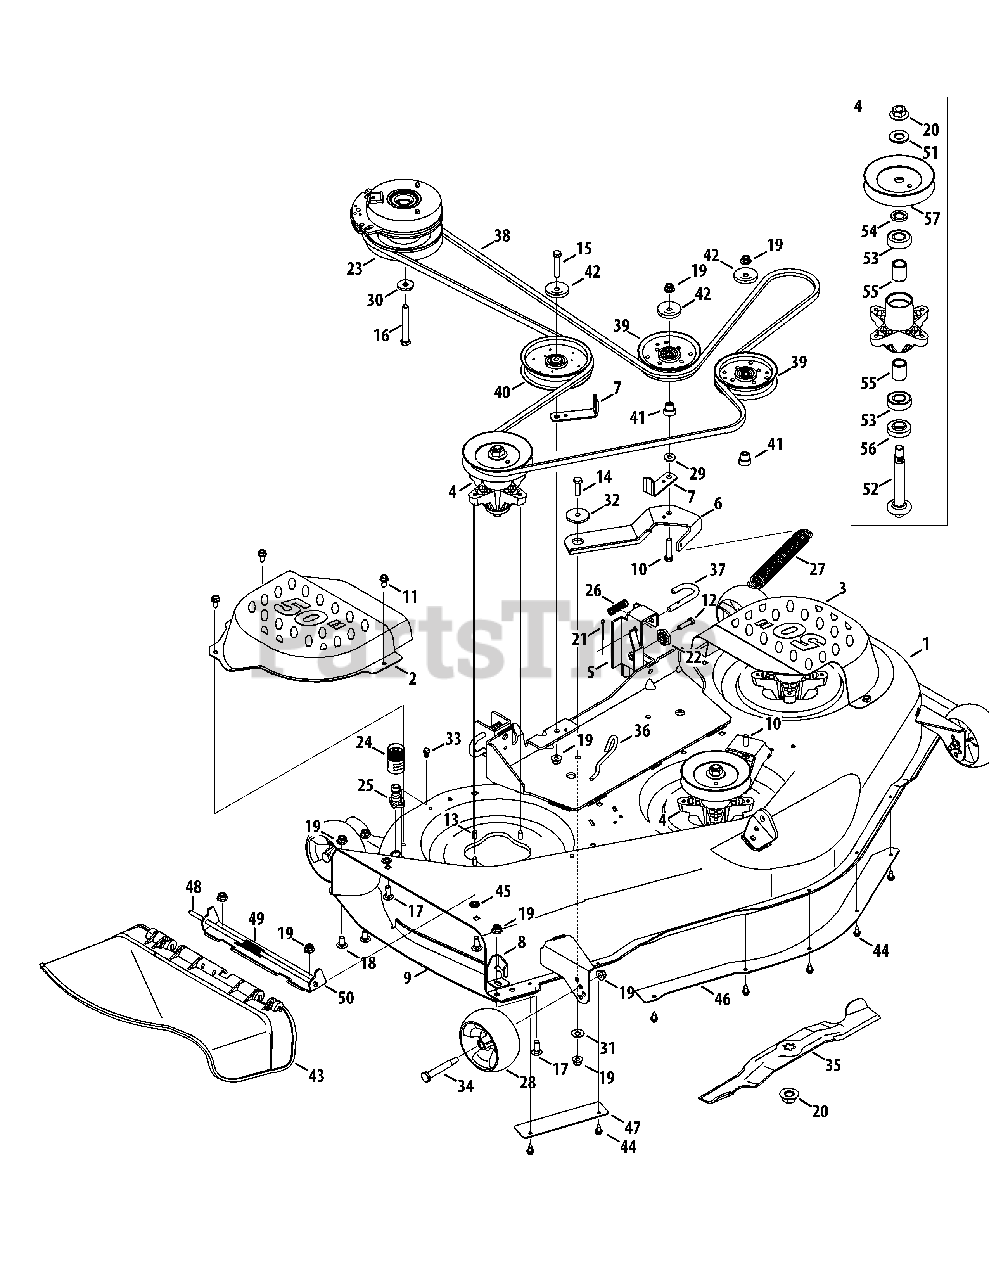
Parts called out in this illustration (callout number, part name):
2	Belt Cover, RH
3	Belt Cover, LH
4	Spindle Assembly
5	Deck Lift Bracket
6	Idler Arm
7	Bracket Belt Guard
10	Hex Cap Screw, 3/8-16 x 1.75
11	Hex Washer Screw, 5/16-18 x .750
12	Hex Cap Screw, 5/16-18 x 1.25
13	Hex Washer Screw, 5/16-18 x .750
14	Hex Cap Screw, 3/8-16 x 1.25
15	Hex Cap Screw, 3/8-16 x 2.00
16	Screw, 7/16-20 x 3.25
17	Carriage Screw, 3/8-16 x 1.00
18	Carriage Screw, 3/8-16 x .75
19	Flange Lock Nut, 3/8-16
20	Hex Flange Nut, 5/8-18
21	Cotter Pin, 5/32 x 1.25
22	Deck Adjustment Gear
23	Electric PTO Clutch
24	Water Nozzle Adapter
25	Deck Wash Nozzle
26	Compression Spring, .66 x 1.9
27	Extension Spring, 1.25 OD x 1.751
28	Deck Ball Wheel, 5.0
29	Flat Washer, .385 x .870 x .092
30	Flat Washer, .450 x 1.25 x .164
31	Bell Washer, .45 x 1.0 x .062
32	Shoulder Spacer, .884 x .190
33	Shoulder Screw, .500 x 1/4-20
34	Shoulder Screw, .5 x 2.5 x 3/8-16
35	Blade, 2 in 1, 17.9
36	Deck Spring Rod
37	Deck Hanger Rod
39	Idler Pulley, 4.25 Dia
40	Idler Pulley, 5.00 Dia.
41	Shoulder Spacer
42	Pulley Cap
43	Discharge Chute Assembly
44	Hex Washer Screw, 1/4-20 x .625
45	Push Nut, 3/8
46	Center Skirt
47	RH Skirt
49	Torsion Spring
50	Chute Bracket
51	Flat Washer, .76 x 1.50 x .12
52	Spindle Shaft, 5.75
53	Ball Bearing
54	Spacer, .79 x 1.25 x .175
55	Spacer, .80 x 1.10 x 1.32
56	Spacer, .79 x 1.82 x .55
57	V-Type Pulley, 5.39
